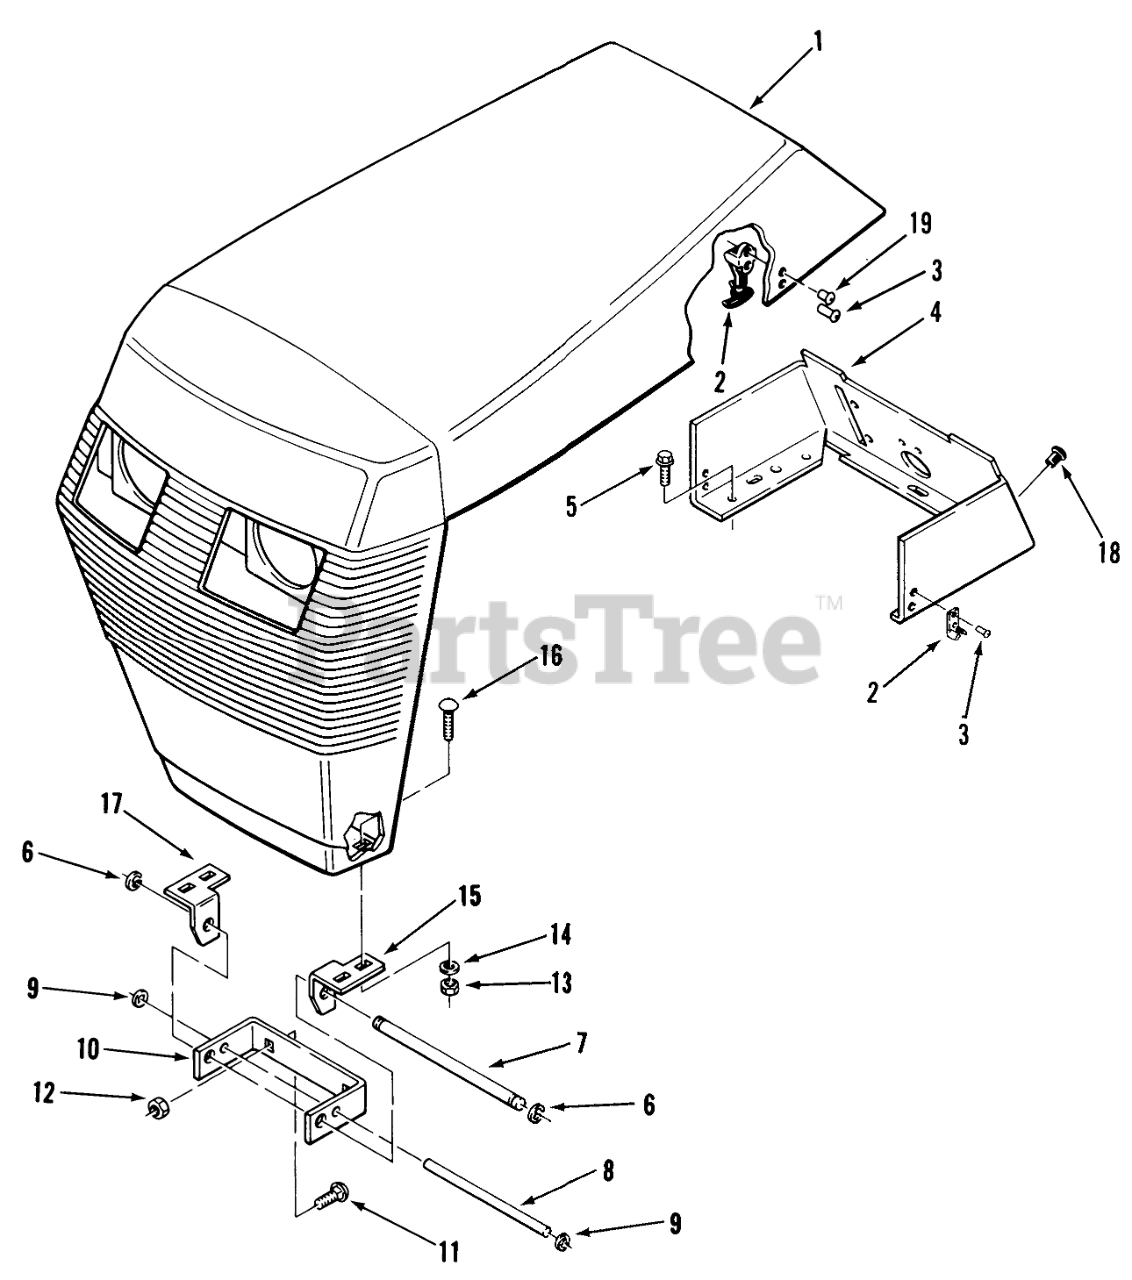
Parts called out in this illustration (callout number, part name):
1	Hood 208-3, 211-3, 211-5
2	ASSY-FLEX DRAW LATCH
3	RIVET -4
4	Console
5	SCREW
6	RING-RETAINING
7	ROD-GRILL PIVOT
8	ROD-HOOD STOP
9	SPEED NUT
10	Bracket Hood Pivot
11	Bolt-Carriage
12	Nut
13	Nut
15	BRKT-GRILL PIVOT R (NS)
16	Bolt-Carriage
17	BRKT-GRILL PIVOT R
18	NYLON PLUG
19	RIVET
